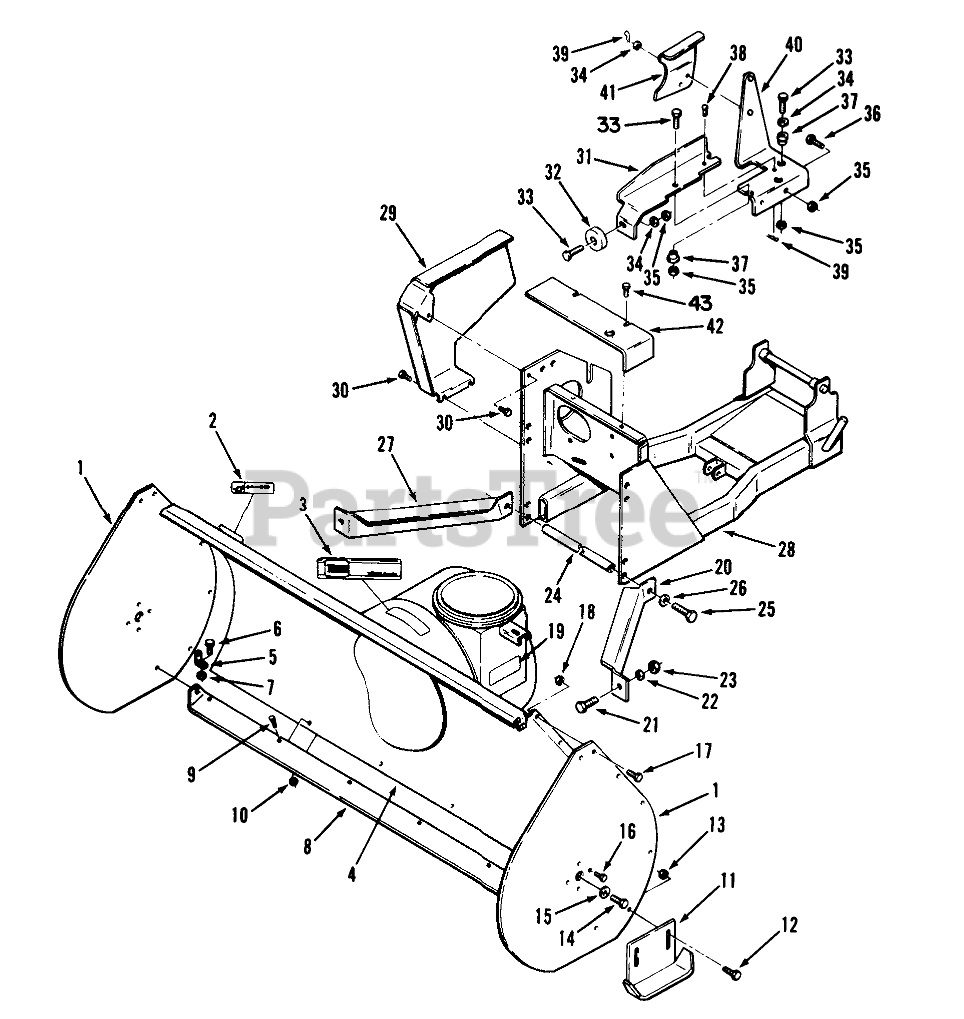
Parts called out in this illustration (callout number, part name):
1	Plate-Side
2	DECAL DANGER
3	DECAL - REAR FRAME
4	Housing-Auger
5	BLADE SUPPORT BRKT R
6	SCREW-HH
7	NUT-LOCK, NI
8	Blade-Scraper
9	SCREW-CARR
10	NUT-LOCK, NI
11	Skid
12	Bolt-Carriage
13	NUT-LOCK, NI
14	SCREW-HH
15	WASHER
16	Bolt
17	SCREW-HH
18	NUT-LOCK, NI
19	DECAL-OVERLAY
20	BRACE-L.H. R
21	CARRIAGE BOLT -4
22	WASHER
23	Nut
24	BRACE-CROSS R
25	SCREW-HH
26	LOCKWASHER
27	BRACE-R.H. R
28	WLDMT-CARRIER FRA R
29	WLDMT-BELT COVER R
30	Bolt
31	BRACKET-BUMPER R
33	SCREW-HH
34	WASHER-FLAT
35	NUT
36	BOLT
37	SPACER-LIFT LINK
38	CLEVIS PIN
39	Hairpin
40	WLDMT-BRKT GUARD R
41	GUARD-BELT R
42	GUARD R
43	Bolt
